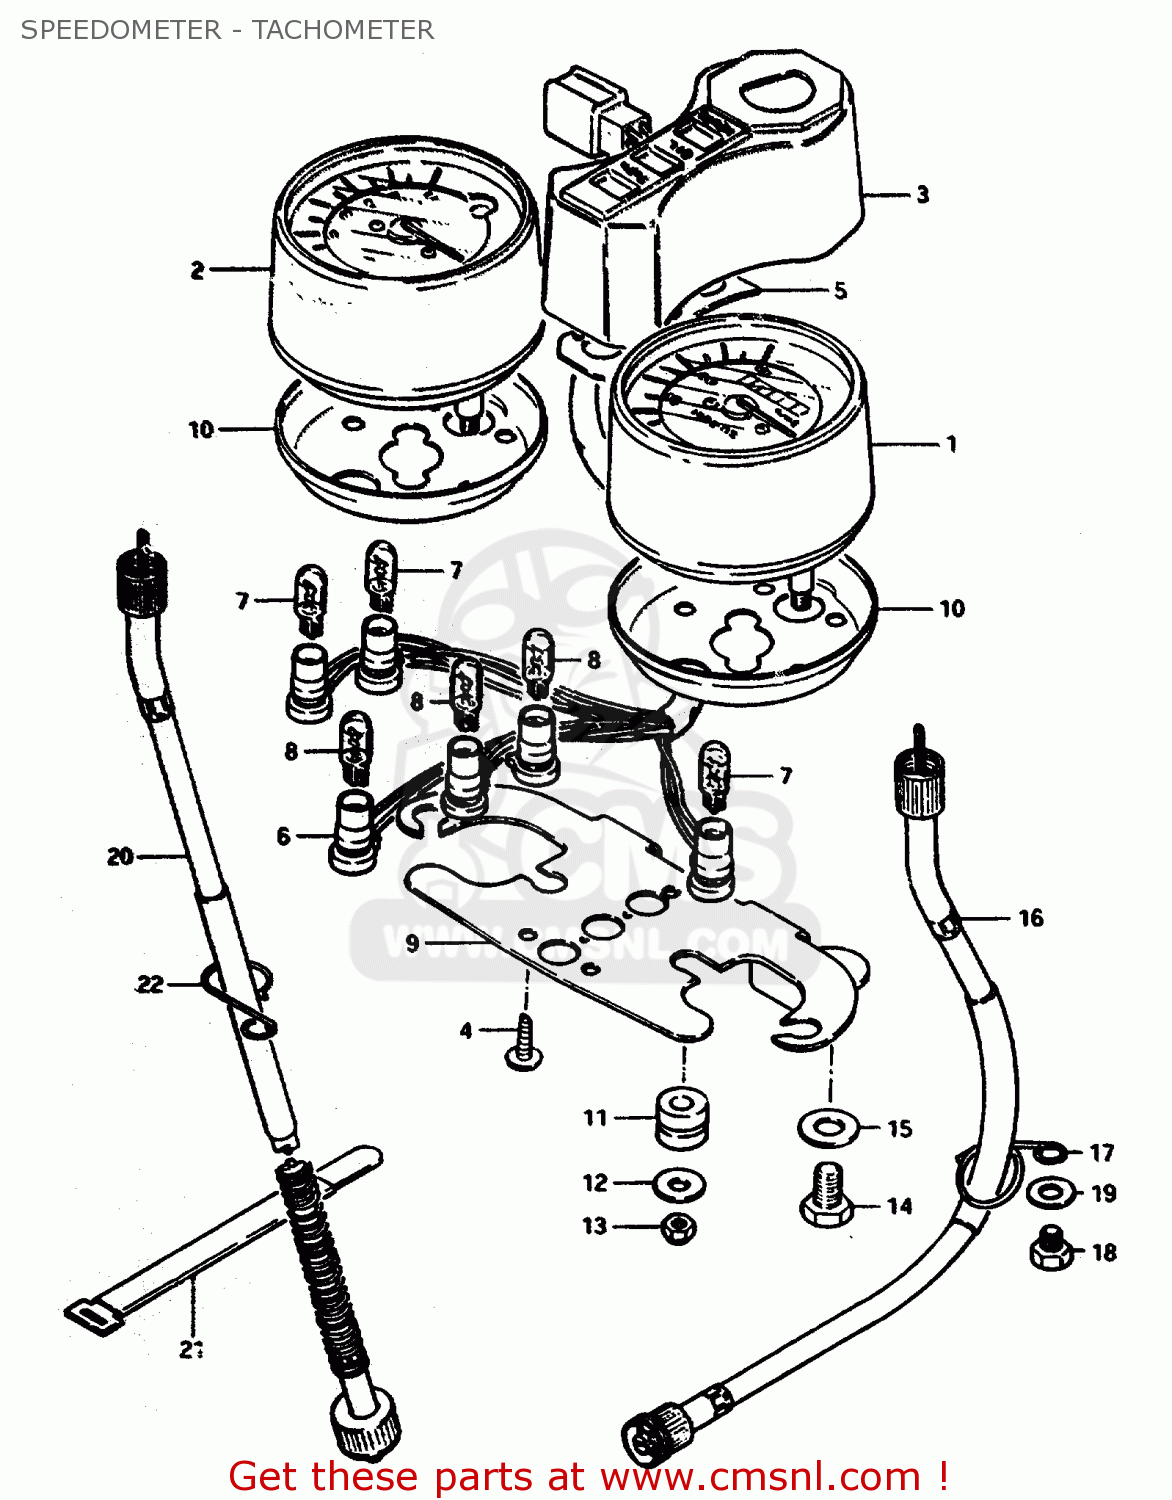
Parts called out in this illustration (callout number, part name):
1	SPEEDOMETER (MILE/KILO)
2	TACHOMETER
3	BOX, PILOT BULB
4	SCREW
5	COVER, PILOT BOX
6	SOCKET
7	BULB(6V1.7W,STANLEY,A61A)
8	BULB(6V,3W)
9	BRACKET
10	ORNAMENT
11	CUSHION,METER
12	WASHER (5.5X16X1.2)
13	NUT
14	BOLT 8X12
15	WASHER
16	CABLE ASSY,SPEEDOMETER
17	CLIP
18	BOLT
19	WASHER
20	CABLE ASSY,TACHOMETER
21	CLAMP
22	CLAMP
